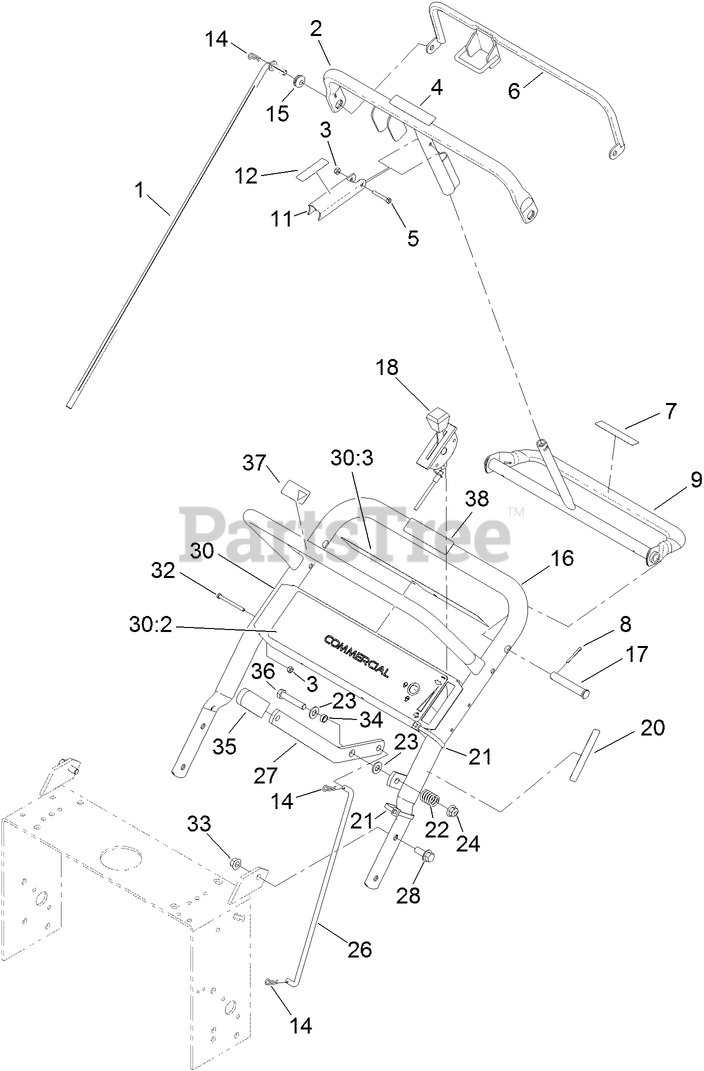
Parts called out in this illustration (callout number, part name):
1	ROD-CONTROL
2	BAR-CONTROL
3	NUT-LOCK, NI
4	DECAL-BAR, CONTROL
5	SCREW-SHH
7	DECAL-REVERSE
8	PIN-COTTER
9	PIVOT-CONTROL
11	LEVER-BRAKE, PARKING
12	DECAL-LEVER, PARKING
14	PIN-COTTER
15	GROMMET-RUBBER
16	HANDLE-UPPER
17	PIN-CLEVIS
18	CABLE-THROTTLE
20	DECAL-ENGAGE, DECK
21	TIE-PLASTIC
22	SPRING-COMPRESSION
23	WASHER-FLAT
24	NUT-HF, NI
26	LINKAGE-DRIVE, BLADE
27	LEVER-ENGAGEMENT, BLADE
28	SCREW-HHF
30	CONTROL PANEL ASM
30:2	DECAL-PANEL, CONTROL
30:3	DECAL-DANGER
32	SCREW-SHH
33	NUT-HF
34	SPACER
35	GRIP-LEVER
36	SCREW-HH
37	DECAL-PROTECTION, EAR
38	DECAL-ARRESTER, SPARK
